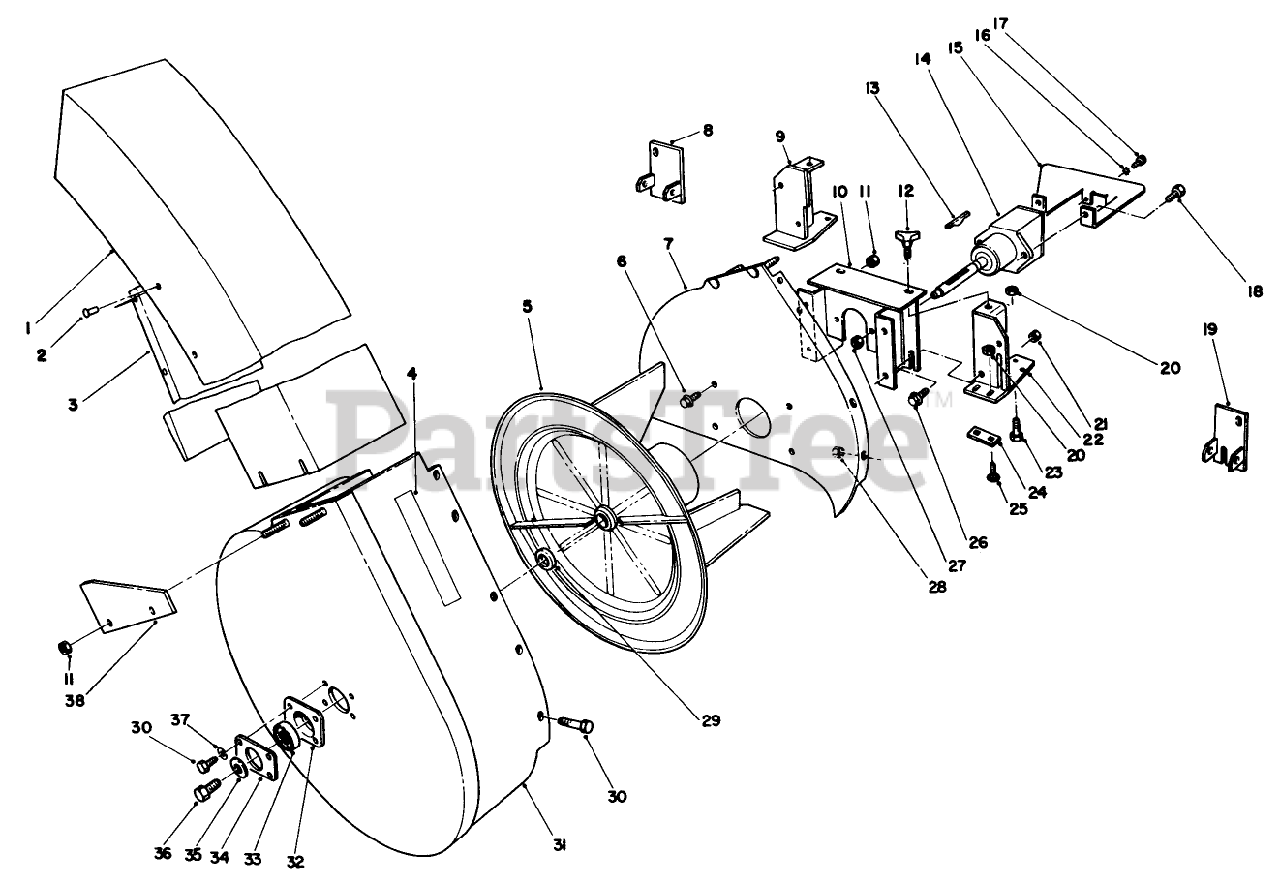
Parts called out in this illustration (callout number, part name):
3	Deflector-Chute
6	SCREW-HH
9	LH BRACKET ASM, WELDED
11	NUT-LOCK, NI
16	WASHER-LOCK, EXT
18	SCREW-HH
20	NUT-LOCK, CONE
21	NUT-JAM
22	RH BRACKET ASM, WELDED
23	SCREW-HH
25	BOLT-CARR
26	SCREW-HHF
27	NUT-LOCK, NI
28	NUT-LOCK, NI
29	SPACER-BEARING
30	SCREW-HH
32	CUP-BEARING
33	BEARING-BALL
35	SPACER
37	SCREW-HH
